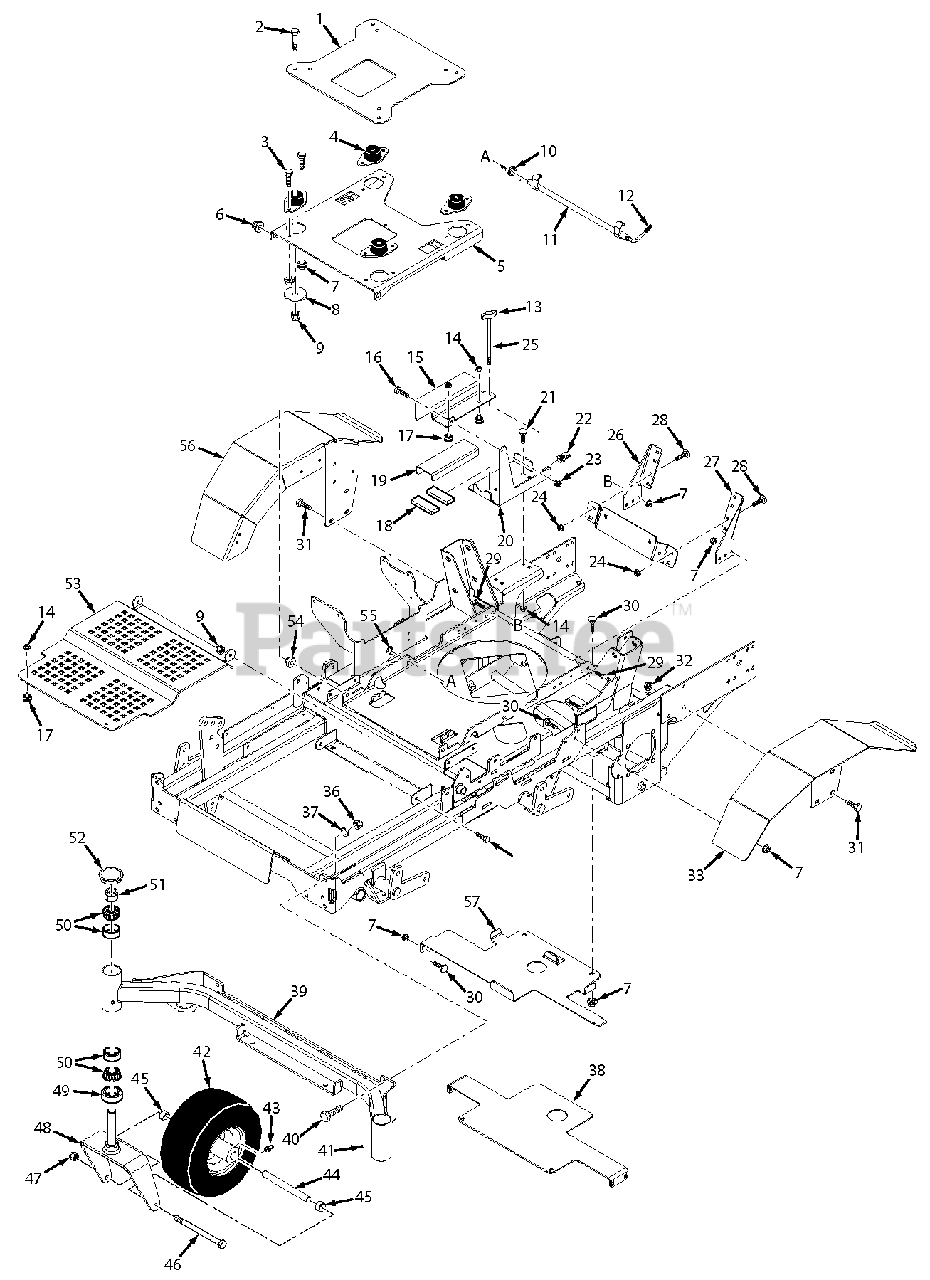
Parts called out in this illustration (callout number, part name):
1	Mounting Plate, Seat
2	Bolt, Hex Head 3/8-16 x 2-1/4"
3	Bolt, Hex Head 5/16-18 x 3/4"
4	Isolator, Seat
5	Seat Mounting Plate, Lower w/Decals
6	Nut, Flange Elastic Stop Nut, 3/8-16
7	Nut, Serrated Flange 3/8-16
8	Flatwasher, 3/8-.406 x 2.25 x .1875
9	Nut, Elastic Stop 3/8-16
10	Spring, Seat Latch
11	Lever Assy., Seat Release
13	Knob, 1/4" Wing
14	Nut, Serrated Flange 5/16-18
15	Cover, Battery Box
16	Bolt, Hex Head 5/16-18 x 3/4"
17	Bumper, Rubber
18	Pad, Rubber
19	Insulation, Battery Cover
20	Battery Box
21	Bolt, Carriage 5/16-18 x 3/4"
22	U-Nut, 1/4-20
23	Nut, Elastic Stop 5/16-18
24	Nut, Serrated Flange 5/16-18
25	Bolt, Hex Head 1/4-20 x 8"
26	Mounting Bracket, Cooler - RH
27	Mounting Bracket, Cooler - LH
28	Bolt, Carriage 1/4-20 x 3/4"
29	Bolt, Hex Head 5/16-18 x 3/4"
30	Bolt, Carriage 5/16-18 x 3/4"
31	Bolt, Hex Head Serrated Flange 3/8-16 x 1"
32	Nut, Serrated Flange 3/8-16
33	Fender, LH
34	Bolt, Hex Head 3/8-16 x 1"
35	Mainframe Assy., w/Decals
36	Nut, Elastic Stop 7/16-14
37	Lockwasher, 7/16"
38	Front Support, Fuel Tank
39	Caster Support Weldment - 52V
39	Caster Support Weldment - 61V
39	Caster Support Weldment - 72V
40	Bolt, Hex Head 7/16-14 x 1-1/4"
41	Pug, Grease Hole
42	Wheel Assembly
42	Bearing
43	Grease Fitting
44	Sleeve, Caster Wheel
45	Spacer, Caster Wheel
46	Bolt, Hex Head 1/2-13 x 9-1/2"
47	Nut, Elastic Stop 1/2-13
48	Yoke Weldment
49	Seal, 2" O.D. x 1.625 Bore
50	Bearing Assembly
51	Nut, Jam 1" - 14
52	Cap, Grease
53	Foot Plate
54	Sleeve, Seat Base Mounting
55	Retaining Ring, .625 Ext. "E"
56	Fender, RH
57	Rear Support, Fuel Tank
